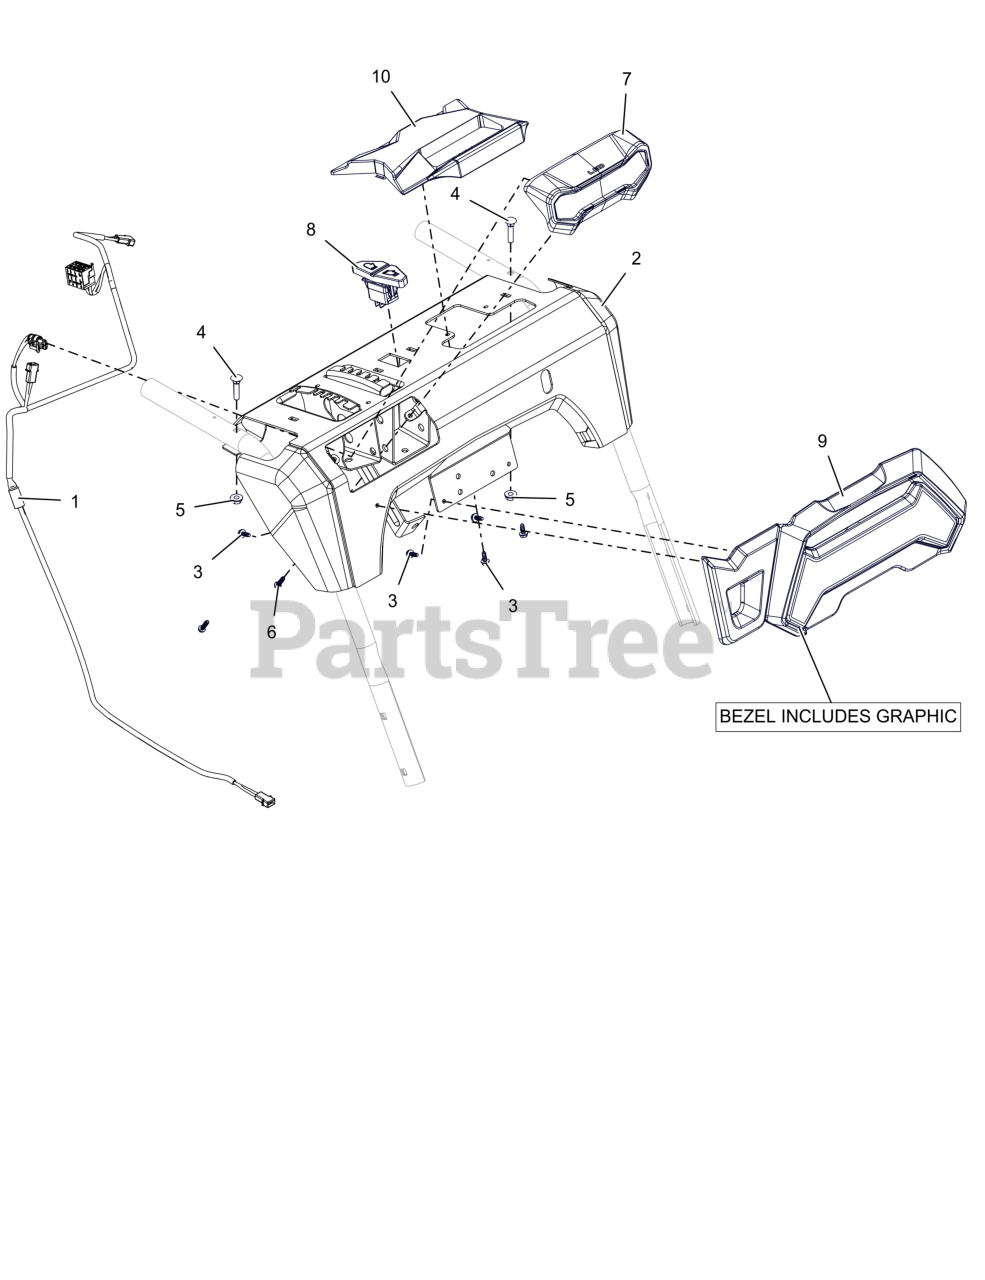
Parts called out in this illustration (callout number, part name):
1	HARNESS- WIRE - LT HG
2	PANEL, CONTROL-EFI ID W/DECAL
3	SCR, PLASTIC #10X.50
4	BLT-RDHDXLSQNK.25-20X1.25 G5ZC
5	NUT-LK-CTR-FLG .25-20 ZC120
6	SCR-HWH 10-16X.75 HI-LO ZCC
7	HEADLIGHT ASM- LED
8	SWITCH- ROCKER SPST-ON/OFF
9	BEZEL- LARGE - PLATINUM
10	BEZEL, OPERATOR CHUTE DECAL
